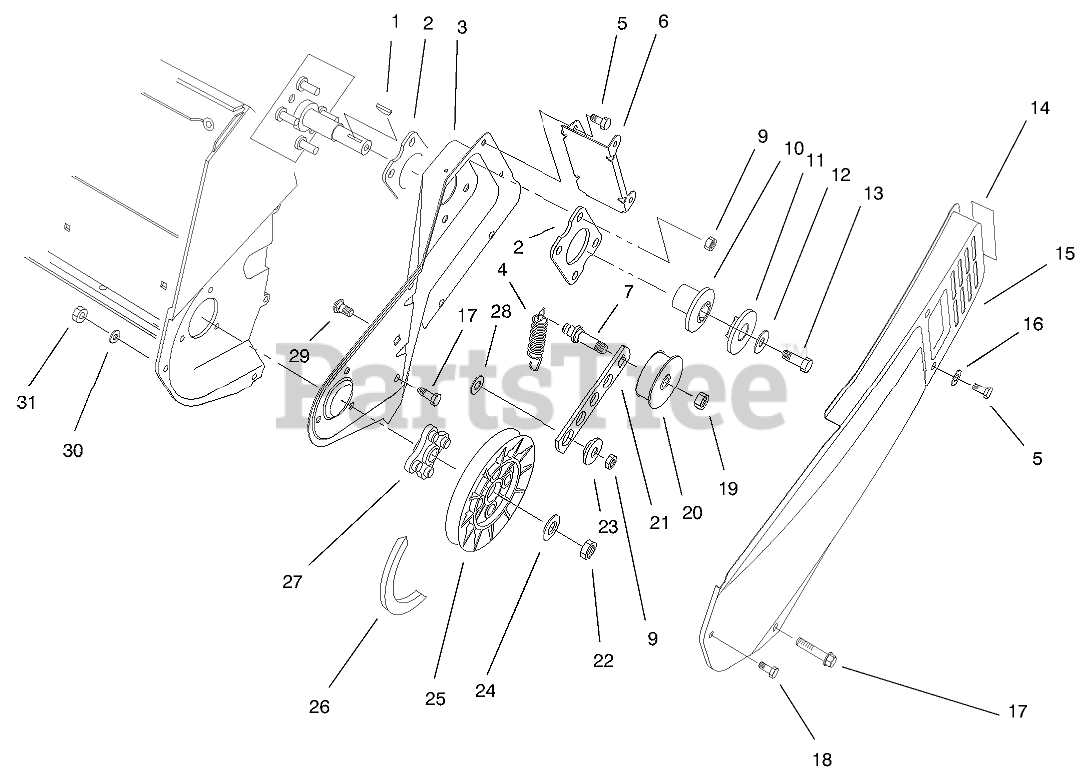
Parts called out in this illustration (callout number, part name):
1	KEY-WOODRUFF
2	PLATE-ENGINE
3	SIDEPLATE-LH
4	SPRING-EXTENSION
5	SCREW-HWH
6	BRACKET-COVER, BELT
7	PIN-IDLER
9	NUT-LOCK, NI
10	Hub-HALF SHEAVE
11	CAP-HALF SHEAVE
12	WASHER-FLAT
13	SCREW-HH
14	Decal-Hot
15	COVER-BELT
16	WASHER-FLAT
17	SCREW-PLASTIC
19	NUT-LOCK, NI
20	PULLEY-IDLER
21	ARM-IDLER
22	NUT-LOCK, NI
23	BUSHING-IDLER
24	WASHER-FLAT
25	PULLEY-DRIVEN
26	V-BELT
28	WASHER
29	SCREW-CARR
30	WASHER-FLAT
31	NUT-LOCK, NI
